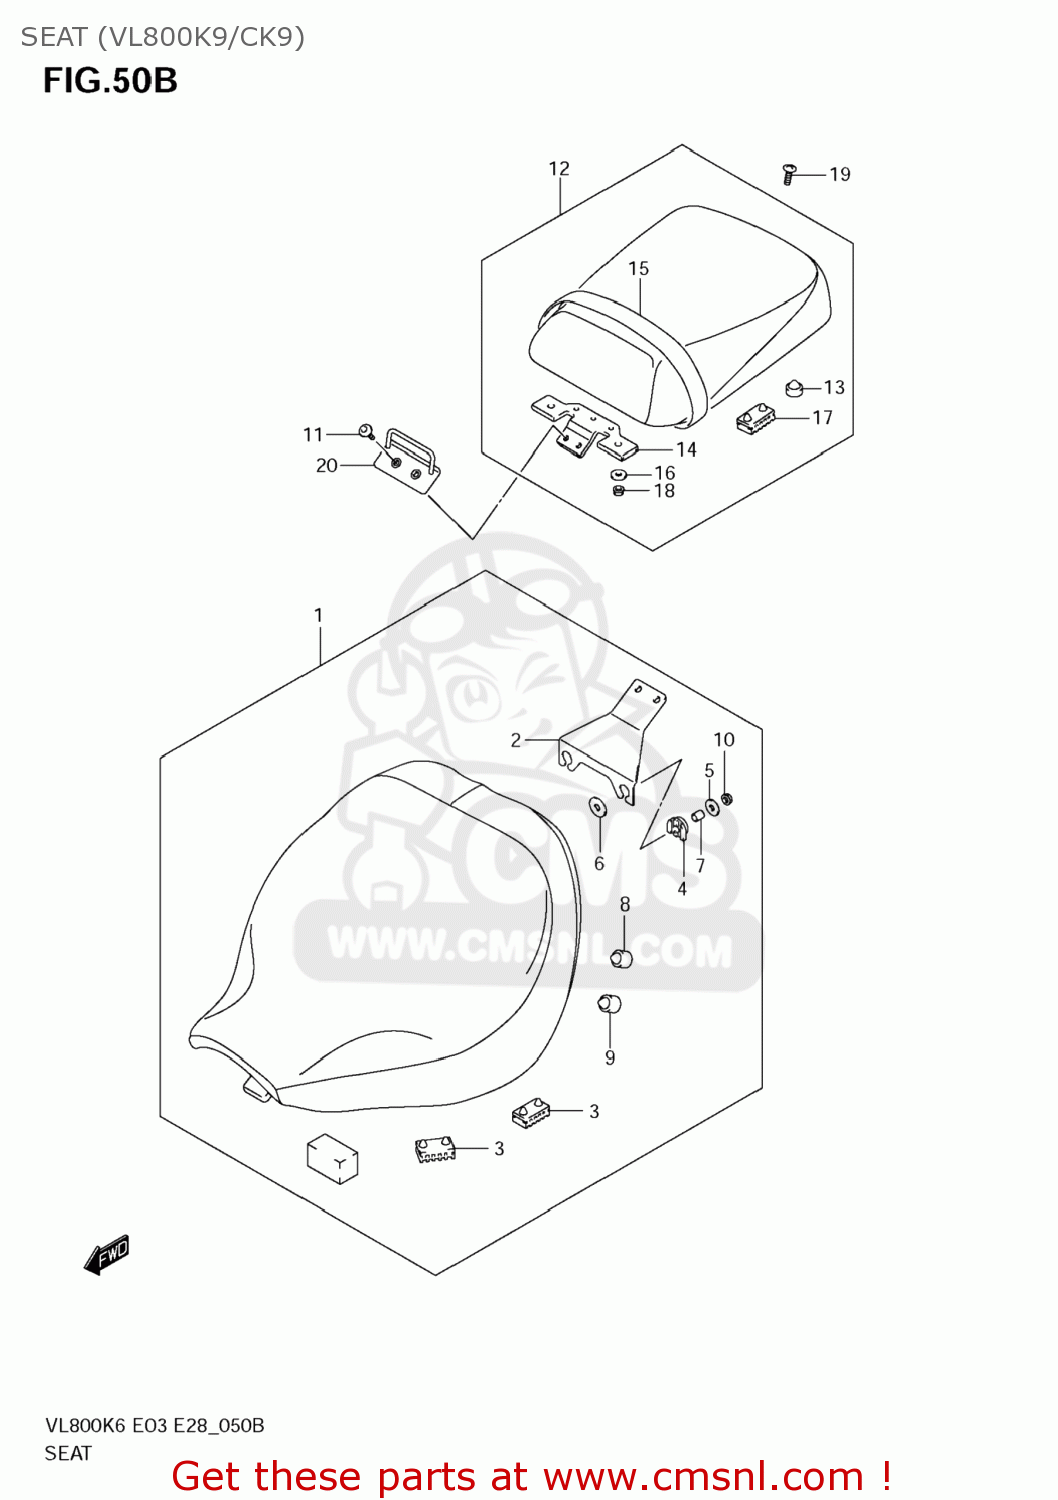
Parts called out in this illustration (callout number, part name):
1	SEAT ASSY
2	BRACKET,SEAT
3	CUSHION,SEAT(40X20X15)
4	CUSHION,SEAT BRACKET
5	WASHER(6.5X20X1.6)
6	WASHER(6.5X24X1.6)
7	SPACER(6.5X10X11)
8	CUSHION(11.5X22X20)
9	CUSHION
10	NUT
11	BOLT(6X18)
12	SEAT ASSY,PILLION
13	CUSHION,RR
14	BRACKET,PILLION SEAT
15	BAND, SEAT PILLION
16	WASHER(6.5X20X1.6)
17	CUSHION(11.5X22X20)
18	NUT
19	BOLT(8X16)
20	BRACKET,SEAT SUPPORT
